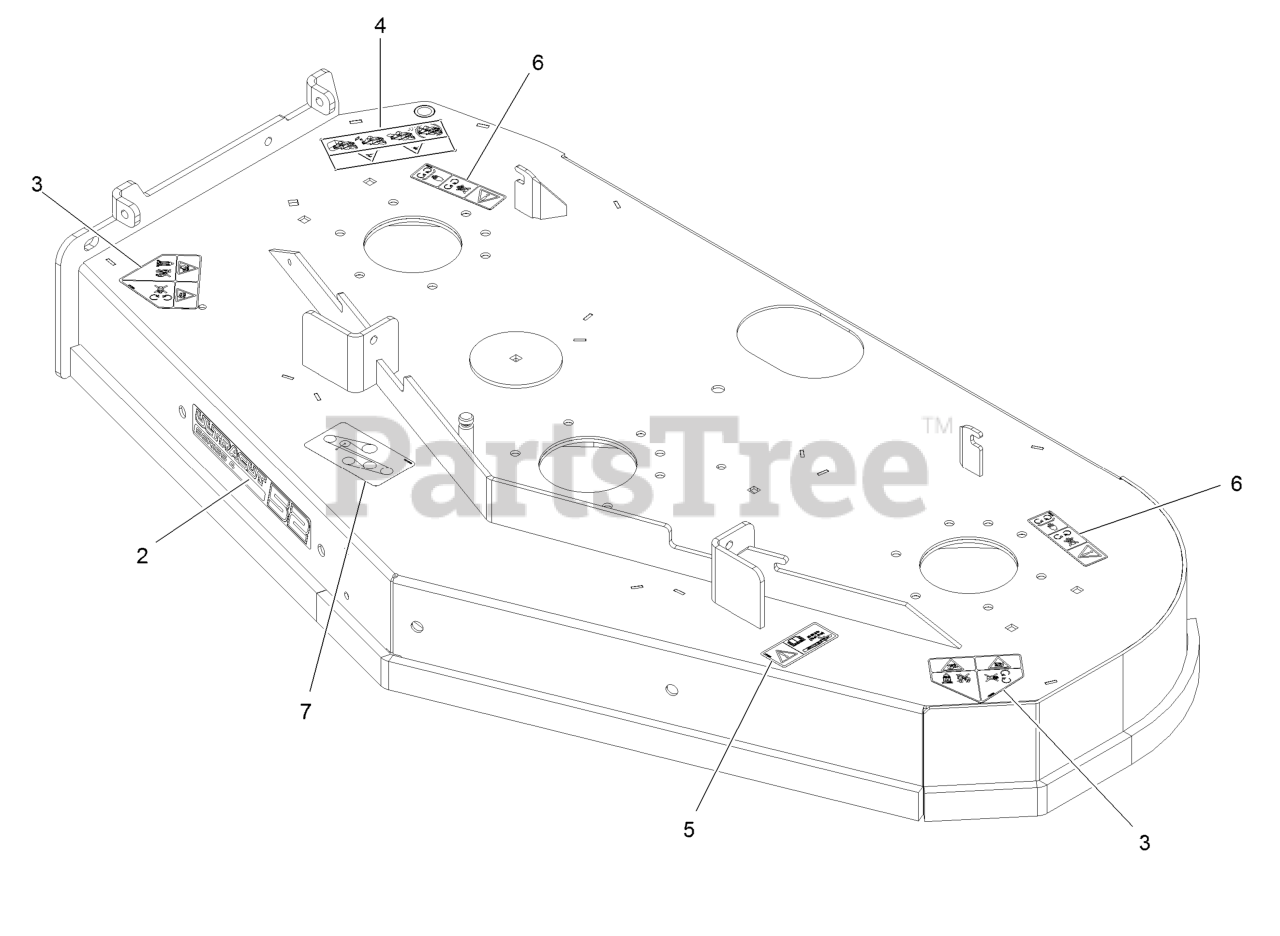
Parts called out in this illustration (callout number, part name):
2	Decal, 524
3	Decal-Danger
4	Decal-Warning, Bagger
5	Decal-Bolt Torque
6	Decal-Missing, Cover
7	Decal-Belt Routing
